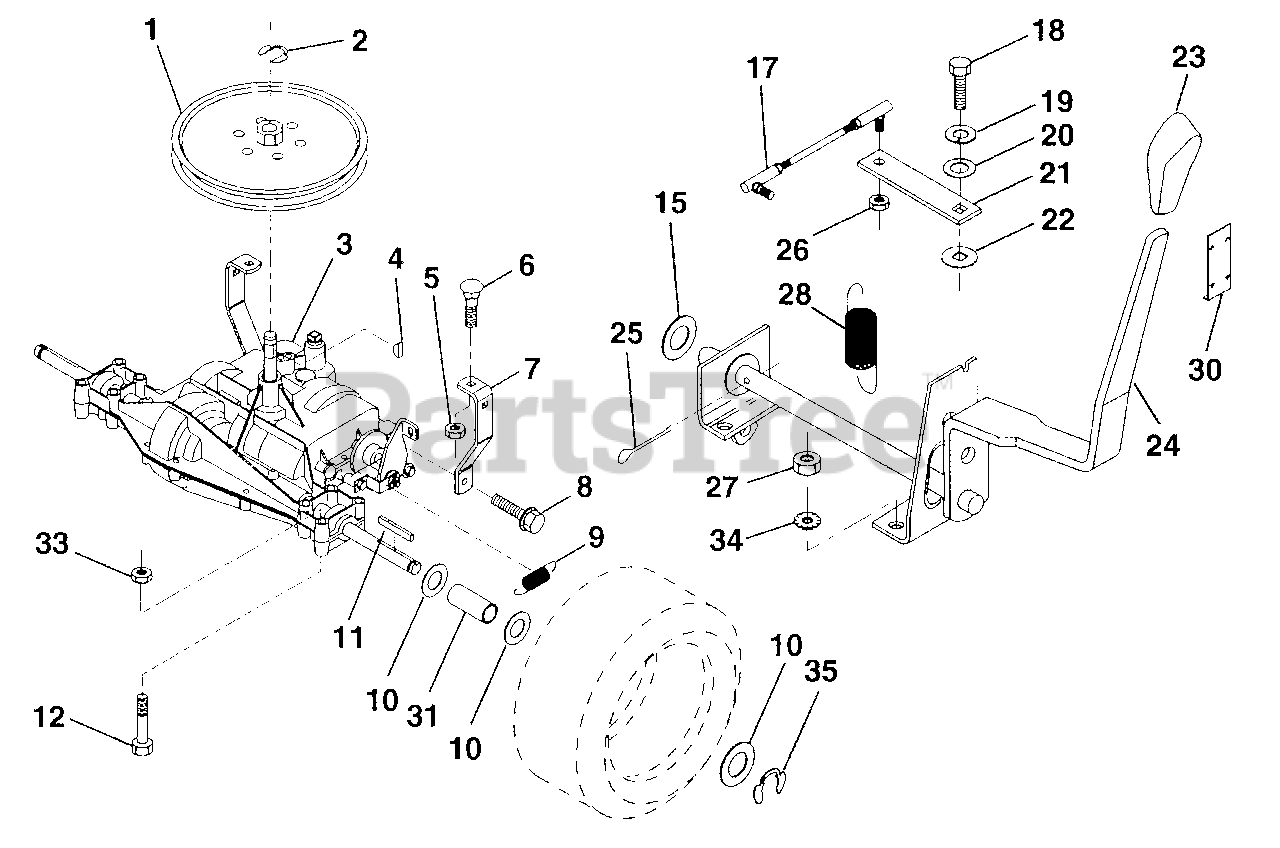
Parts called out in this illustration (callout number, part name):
1	Pulley (AYP part number)
2	Ring, Retainer (AYP part number)
3	Transaxle, Dana, 6 Speed, Model Number 4360-18 (AYP part number)
4	Key, Woodruff #9 (AYP part number)
5	Nut, Crownlock 5/16-18
6	Bolt, Carriage 5/16-18 UNC x 3/4
7	Strap, Torque (AYP part number)
8	Screw, Hex, Thd. Roll. 5/16-18 x 3/4
9	Spring, Brake (AYP part number)
10	Washer 25/32 x 1-1/4 x 16 Gauge (AYP part number)
11	Key, Square (AYP part number)
12	Bolt, Hex 3/8-16 x 2-3/4 (AYP part number)
15	Washer 17/32 x 1 x 16 Gauge (AYP part number)
17	Link, Shift (AYP part number)
18	Bolt, Hex, Fin. 1/4-28 x 3/4 Gr. 8 (AYP part number)
19	Washer, Lock 1/4 (AYP part number)
20	Washer 9/32 x 3/4 x 10 Gauge (AYP part number)
21	Arm, Shift (AYP part number)
22	Washer, Shift Plate (AYP part number)
23	Knob (AYP part number)
24	Rod, Shift
25	Pin, Cotter 1/8 x 1 (AYP part number)
26	Nut, Hex Head, Nylon 5/16-24 (AYP part number)
27	Nut, Keps 5/16-18 (AYP part number)
28	Spring, Extension (AYP part number)
30	Retainer, Knob (AYP part number)
31	Spacer (AYP part number)
33	Nut, Crownlock 3/8-16
34	Washer, Lock, External Tooth 5/16 (AYP part number)
35	E-Ring (AYP part number)
